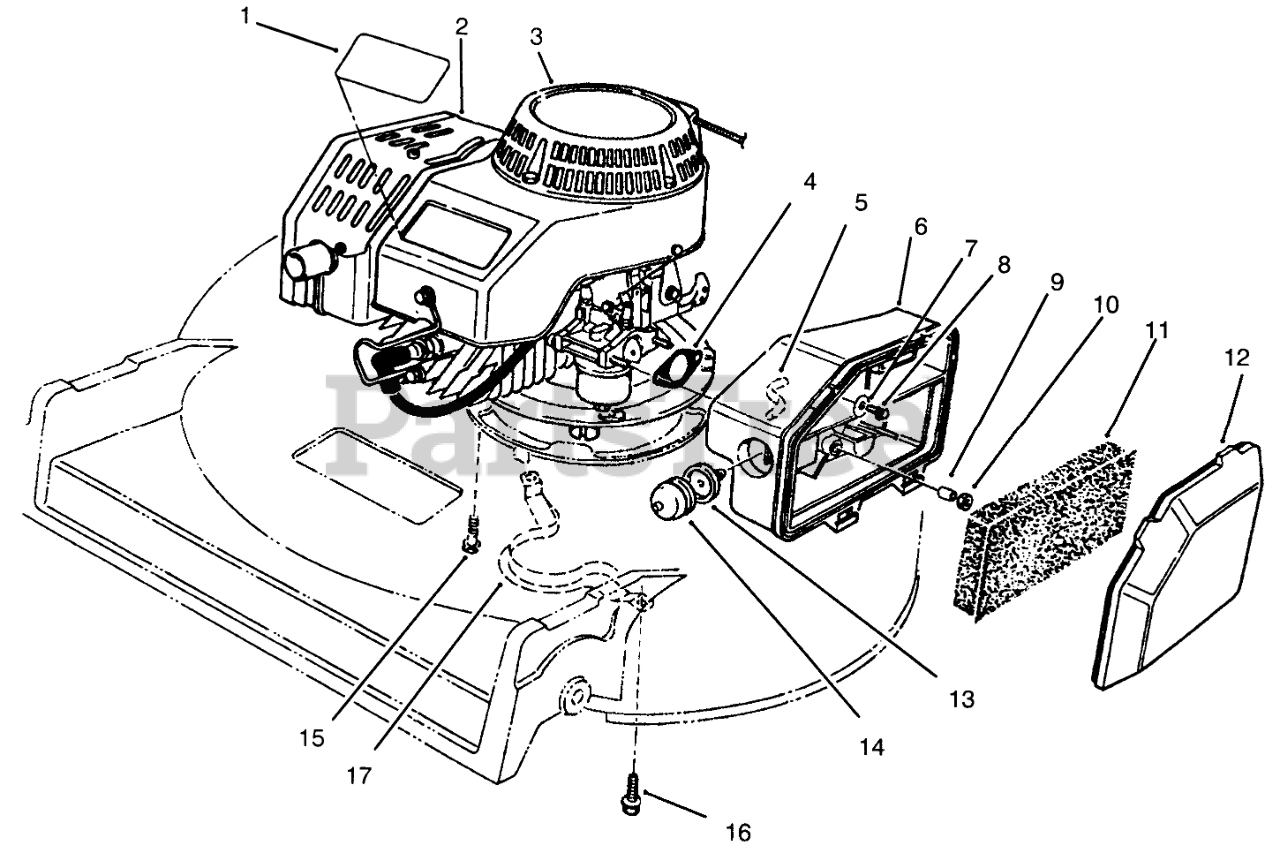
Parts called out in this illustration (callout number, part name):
1	DECAL - PROLINE
2	ENGINE ASM - BBC 2 CYCLE
3	DECAL-2 CYC RECOIL COMM
4	GASKET-AIR CLEANER
5	HOSE-PRIMER
6	BODY-AIR CLEANER
7	WASHER-FLAT
8	SCREW-HH
9	SPACER
11	ELEMENT-AIR CLEANER
12	COVER-AIR CLEANER
13	BODY-PRIMER
14	BULB-PRIMER
15	SCREW-HHF
16	SCREW-HWHTF
17	Guide-Belt
